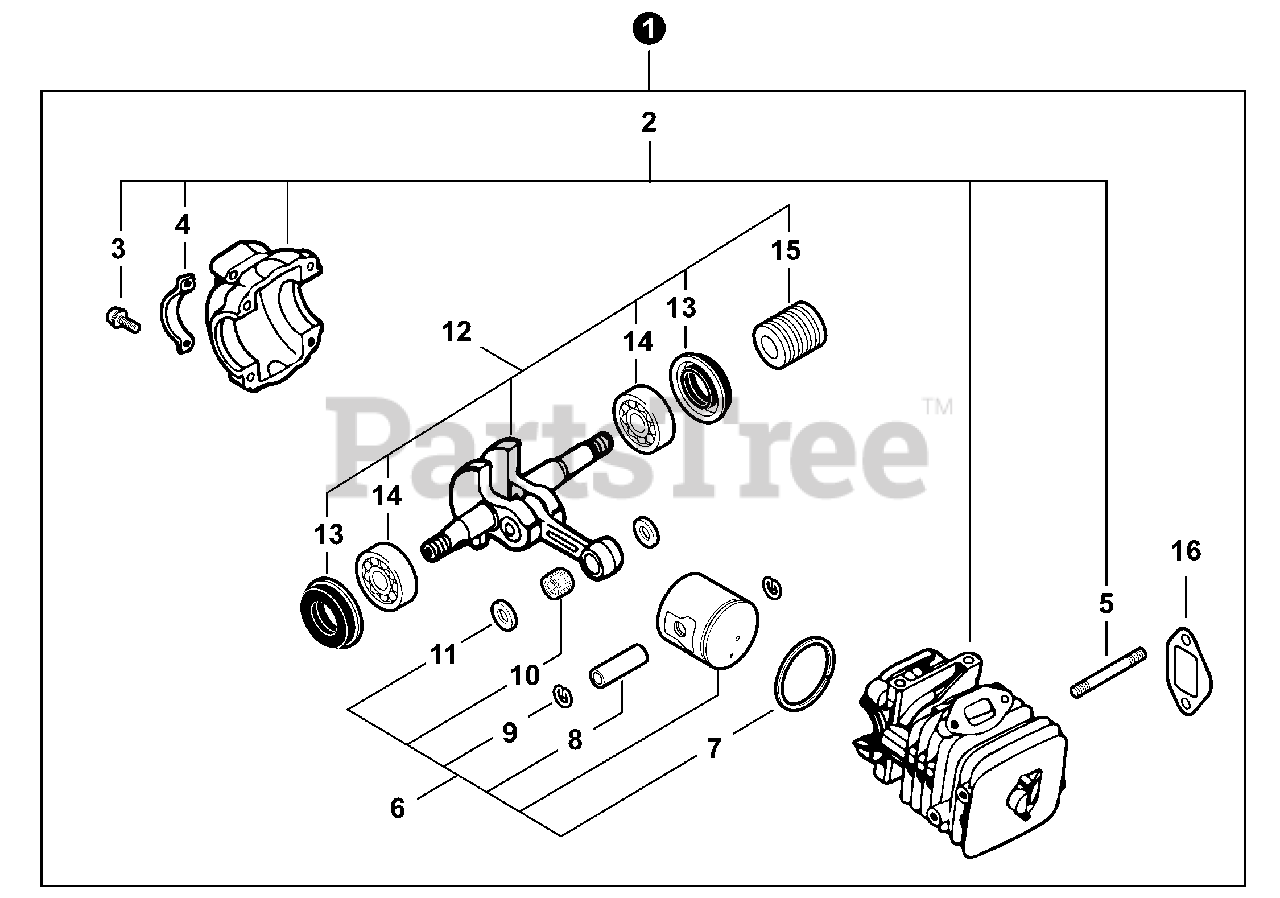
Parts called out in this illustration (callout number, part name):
1	SHORT BLOCK
2	CRANKCASE KIT
3	SCREW 5×25
4	BRACKET, CRANKCASE
5	BOLT, STUD
6	PISTON KIT
7	RING, PISTON
8	PIN, PISTON
9	RING, SNAP
10	BEARING, NEEDLE 8
11	WASHER, THRUST
12	CRANKSHAFT ASSY
13	SEAL, OIL 12
14	BEARING, BALL - 6201 C3
15	GEAR, WORM
16	GASKET, EXHAUST
